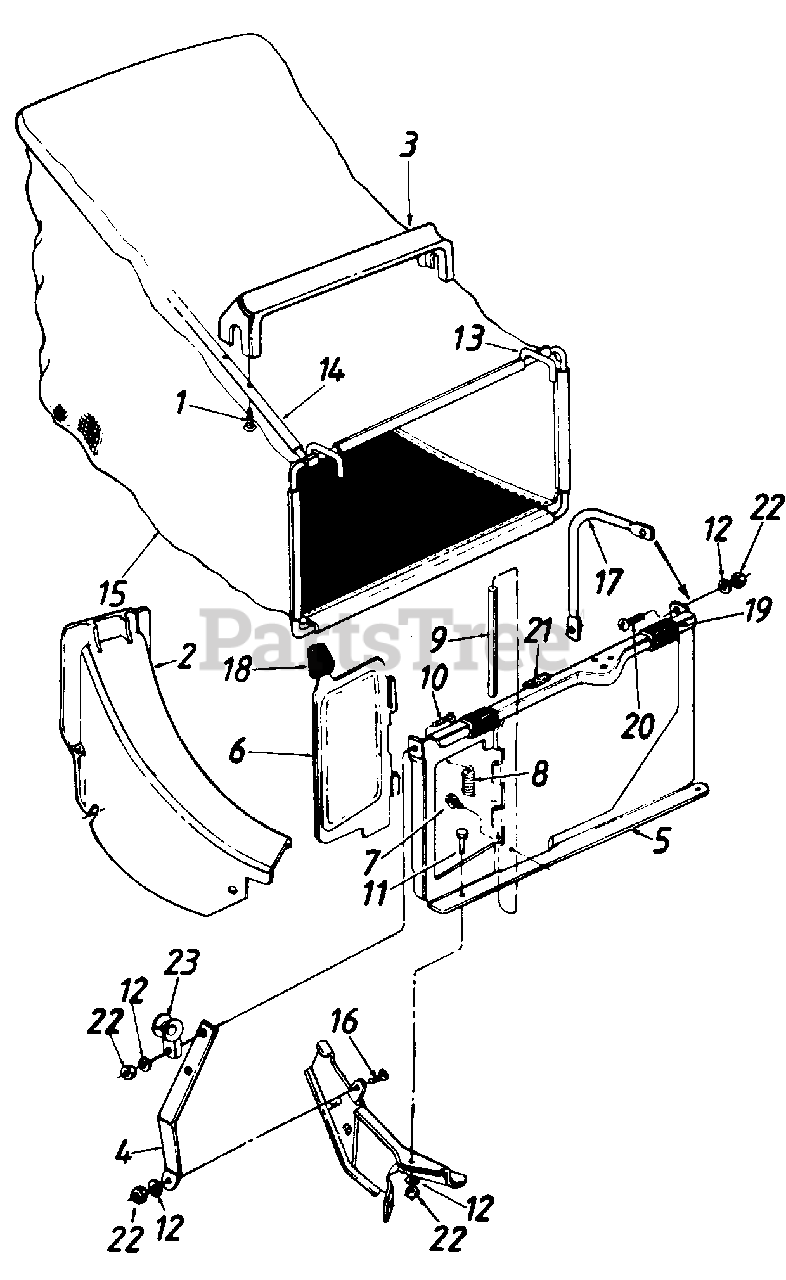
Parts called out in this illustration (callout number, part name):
1	Hex AB-Tap Scr. #12 x 1.25n Lg.
2	N Rear Discharge Chute Ass'y.
3	Bag Handle
7	Hex B-Tap Scr. #10 x 38n
8	N Torsion Spring
9	Pivot Pin
10	Truss Mach. Scr. 1/4-20 x V4n Lg.
11	Hex Bolt 1/4-20 x .50" Lg.
12	L-Wash. 1/4" I.D.
15	21" Rear Discharge Grass Bag
16	Hex Bolt 1/4-20 x .62" Lg.
17	N Catcher Panel Support Arm
18	Door Grip
19	N Panel Clip
20	Truss Mach. Scr. 1/4-20 x .62" Lg.
21	Foam Strip
22	Hex Nut 1/4-20 Thd.
23	Rope Guide
